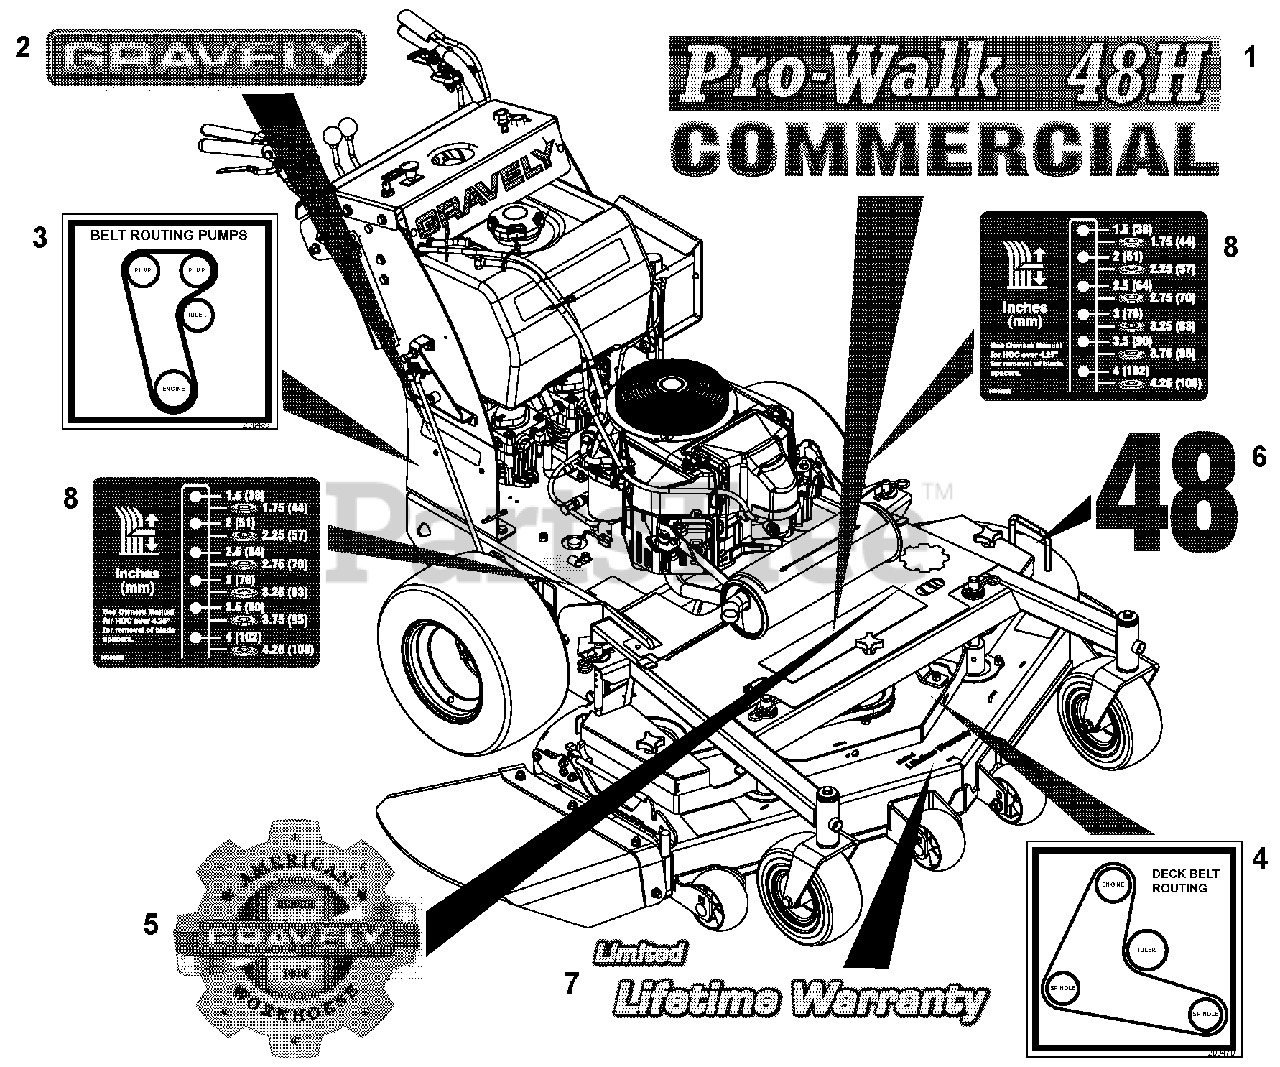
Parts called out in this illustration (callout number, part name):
1	Decal, Gravely Pro-Walk 36H (988323)
1	Decal, Gravely Pro-Walk 48H (988324)
1	Decal, Gravely Pro-Walk 52H (988325)
2	Decal, Gravely 6.5"
3	Decal, Pump Belt Routing
4	Decal, 36" Deck Belt Routing (988323)
4	Decal, 48/52" Deck Belt Routing (988324, 325)
5	Decal, Gravely Heritage
6	Decal, Deck Size 36" (988323)
6	Decal, Deck Size 48" (988324)
6	Decal, Deck Size 52" (988325)
7	Decal, Limited Lifetime Warranty
8	Decal, Prowalk HOC
